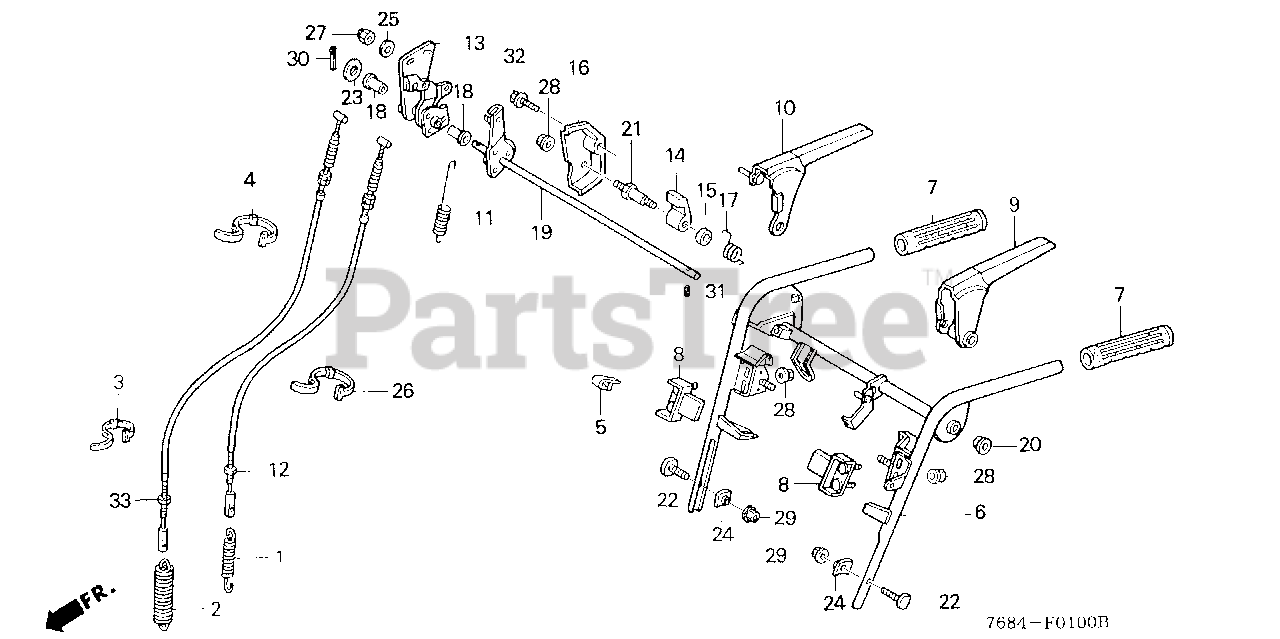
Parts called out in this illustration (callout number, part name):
1	SPRING, TENSIONER ROLLER
2	SPRING, TENSIONER ROLLER (AUGER)
3	BAND B1, WIRE
4	BAND B1, WIRE
5	RUBBER, STOPPER
6	PIPE, HANDLE (UPPER)
7	GRIP, HANDLE
8	STOPPER, CHANGE LEVER
9	LEVER, CLUTCH
10	LEVER, AUGER CLUTCH
11	SPRING, CLUTCH LEVER
12	CABLE, CLUTCH
13	BOSS, CAM LOCK
14	RATCHET, LEVER
15	COLLAR, RATCHET
16	COVER, RATCHET
17	SPRING, RATCHET
18	BUSH (13X22.5) (GRAY)
19	SHAFT, CLUTCH LEVER
20	BUSH (14MM)
21	BOLT, PIVOT (6MM)
22	BOLT, HANDLE HOLDER (8X41)
23	WASHER, THRUST (10MM)
24	WASHER, FRAME JOINT
25	WASHER (6MM)
26	BAND, WIRE HARNESS
27	NUT, CAP (6MM)
28	NUT, FLANGE (6MM)
29	NUT, FLANGE (8MM)
30	PIN, SPLIT (3.0X18)
31	PIN, SPRING (4X16)
32	BOLT, FLANGE (6X10)
33	CABLE, CLUTCH
